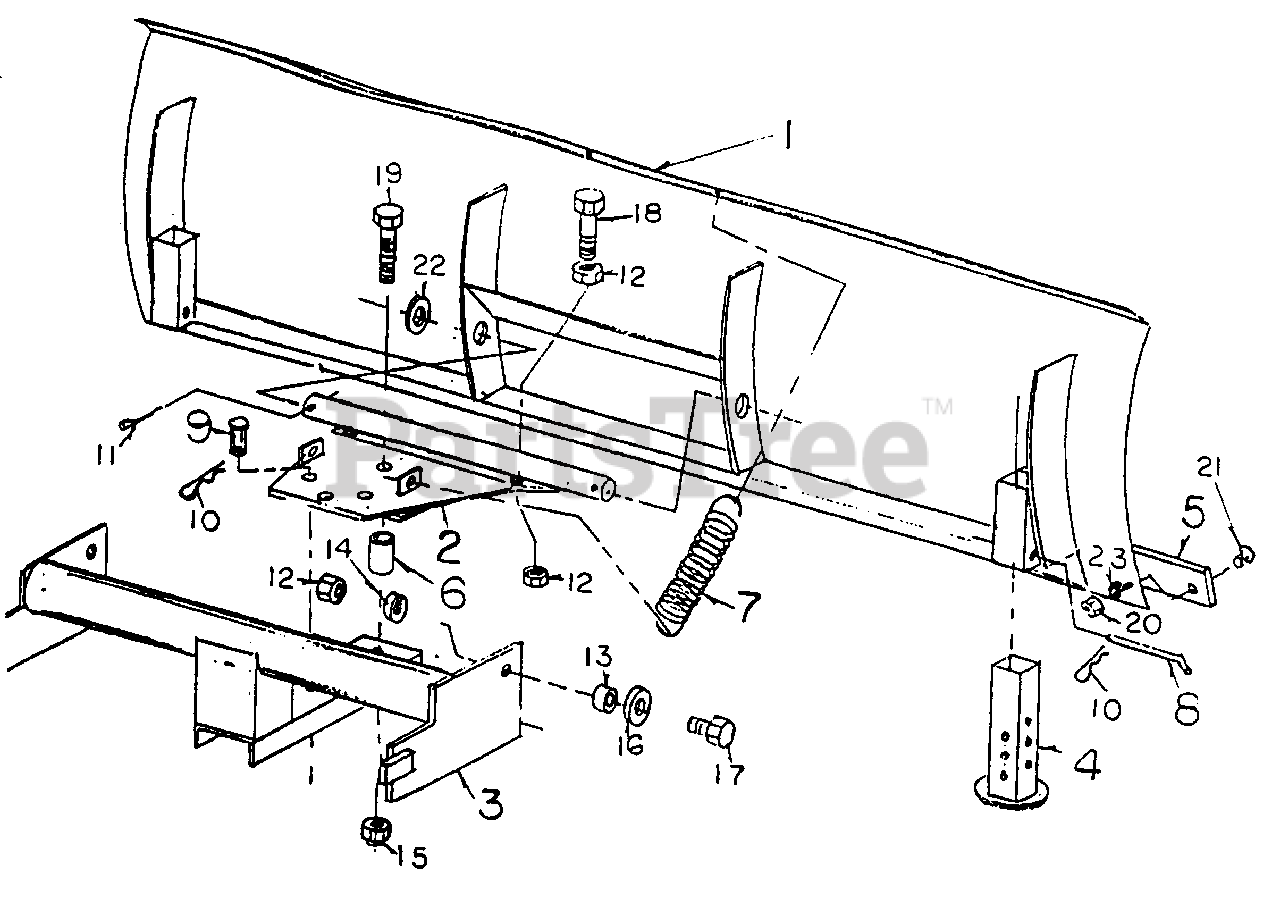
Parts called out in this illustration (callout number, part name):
1	54" B1ade
3	54" Blade Mount
5	Replaceable Blade
11	3/16 Cotter Pin
12	1/2-13 Nut
13	Bushing
14	1/2 Lock Washer
15	1/2 Lock Nut
16	1/2 Flat Washer
17	1/2-13 x l-l/2
18	1/2-13 x 2-1/4
19	1/2-13 x 3
20	? 5/16-18 Nut
21	5/16-18 x 1 Carg.
23	5/16 Lock Washer
